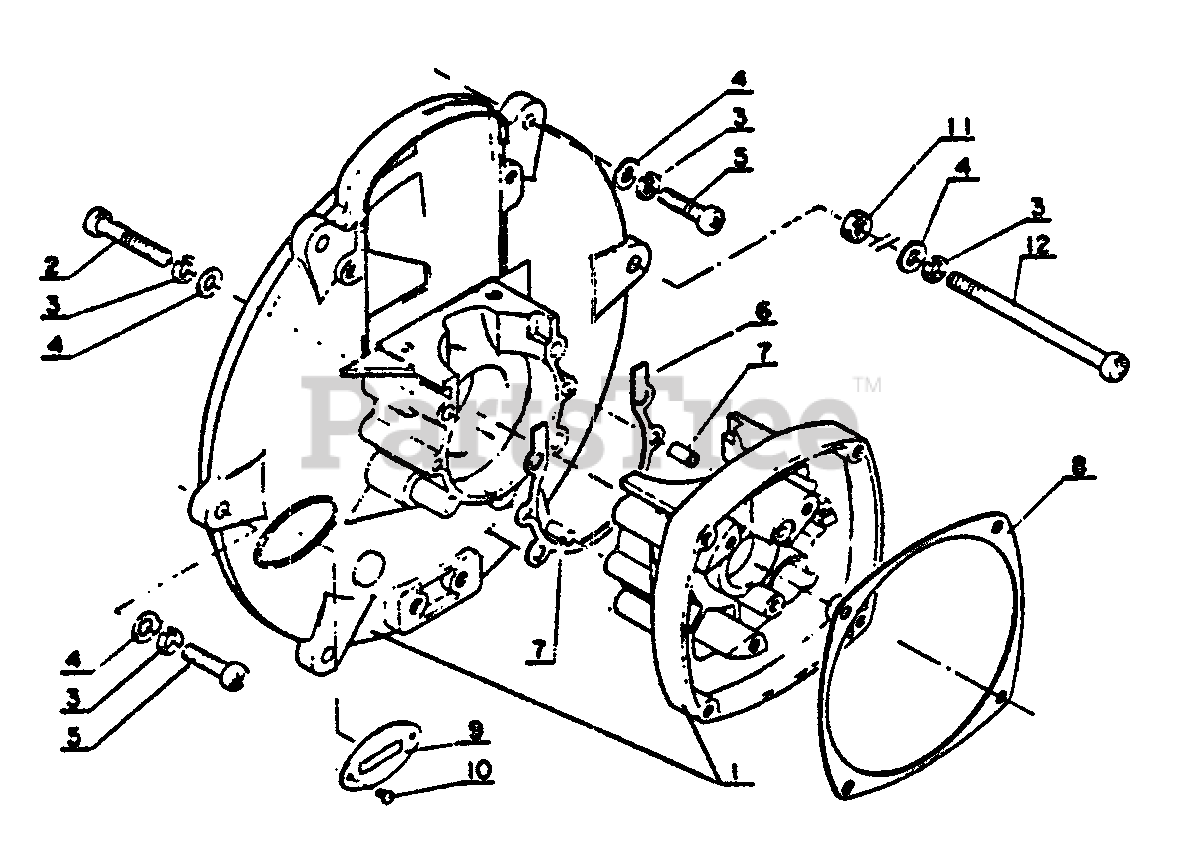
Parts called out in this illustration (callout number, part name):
1	CRANKCASE KIT
2	SCREW - 5X28
3	LOCKWASHER - 5
4	WASHER - 5
5	SCREW - 5X18
6	GASKET, CRANKCASE
7	PIN - LOCATING
8	GASKET, STARTER
9	PLATE, MODEL
10	RIVET
12	SCREW - 5X70
